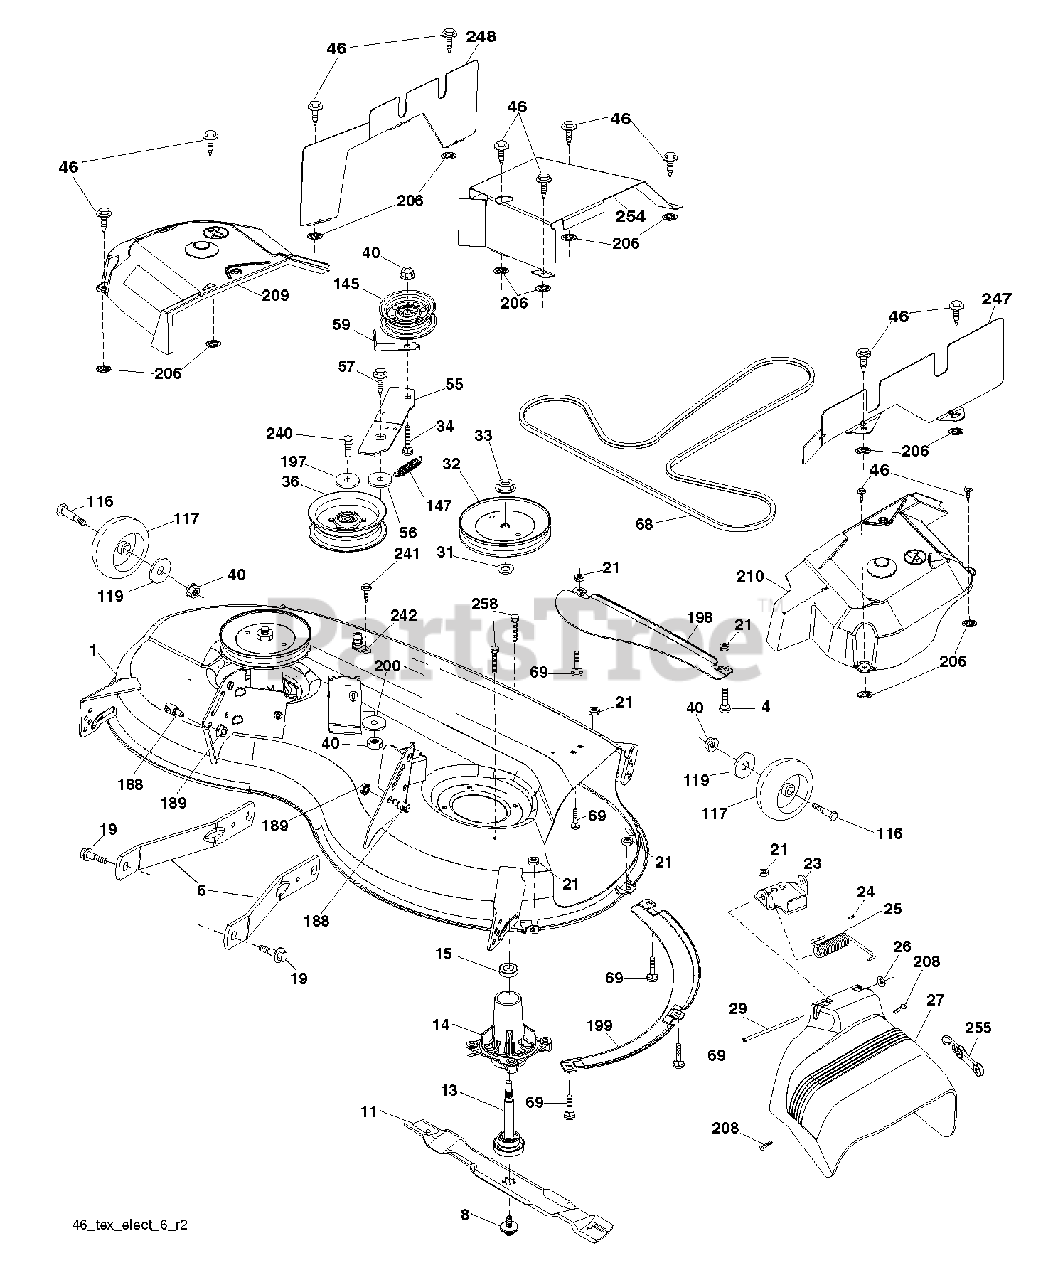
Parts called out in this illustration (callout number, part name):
4	BOLT
6	ARM.SUSPENSION.MOWER.R
8	BOLT.WASHER.ASM.7/16-2
11	BLADE 46" HI LIFT
13	SHAFT.ASM.MDRL.N/GREASE.38
14	HOUSING MANDREL
19	BOLT.SHOULDER
21	LOCKNUT
23	BRKT.DEFLECTOR.38"2005+
24	CAP-SLEEVE LT
25	SPRING.TORSION.DEFLECT
26	NUT PUSH M
29	ROD.HINGE
31	WASHER.SPACER.MANDREL
32	PULLEY.MANDREL.5.438.PD
33	NUT.FLANGE.LOCK.TOP
34	BOLT.3/8-16X1.50
36	PULLEY.IDLER.2006
40	NUT LOCK FLG 3/8-16 UNC
46	SCREW.1/4-20X5/8
55	IDLER.ARM
56	SPACER.RETAINER
57	SCREW 3/8-16X1
59	GUARD, BELT
68	V BELT
69	BOLT
116	BOLT.SHOULDER.3/8-16X3-5/8
117	WHEEL. GUAGE RALLY
145	PULLEY.IDLER.48"PRIMARY
147	SPRING.MOWER.DRIVE.ELECTRIC
188	STUD.FASTNER.W/ANTI-ROTATE
189	NUT LOCK HEX FLANGE 5/16-18
197	WASHER
198	BAFFLE CENTER FRONT
199	BAFFLE FRONT RH
200	WASHER.13/32 X 1 X 1/2.11GUARD
206	PALNUT 1/4
208	SCREW 3/8-16X1/2
240	BOLT-HEX EAK
242	PORT.WASHOUT
258	Hex Washer Head Bolt, .313-18 X 1.19
